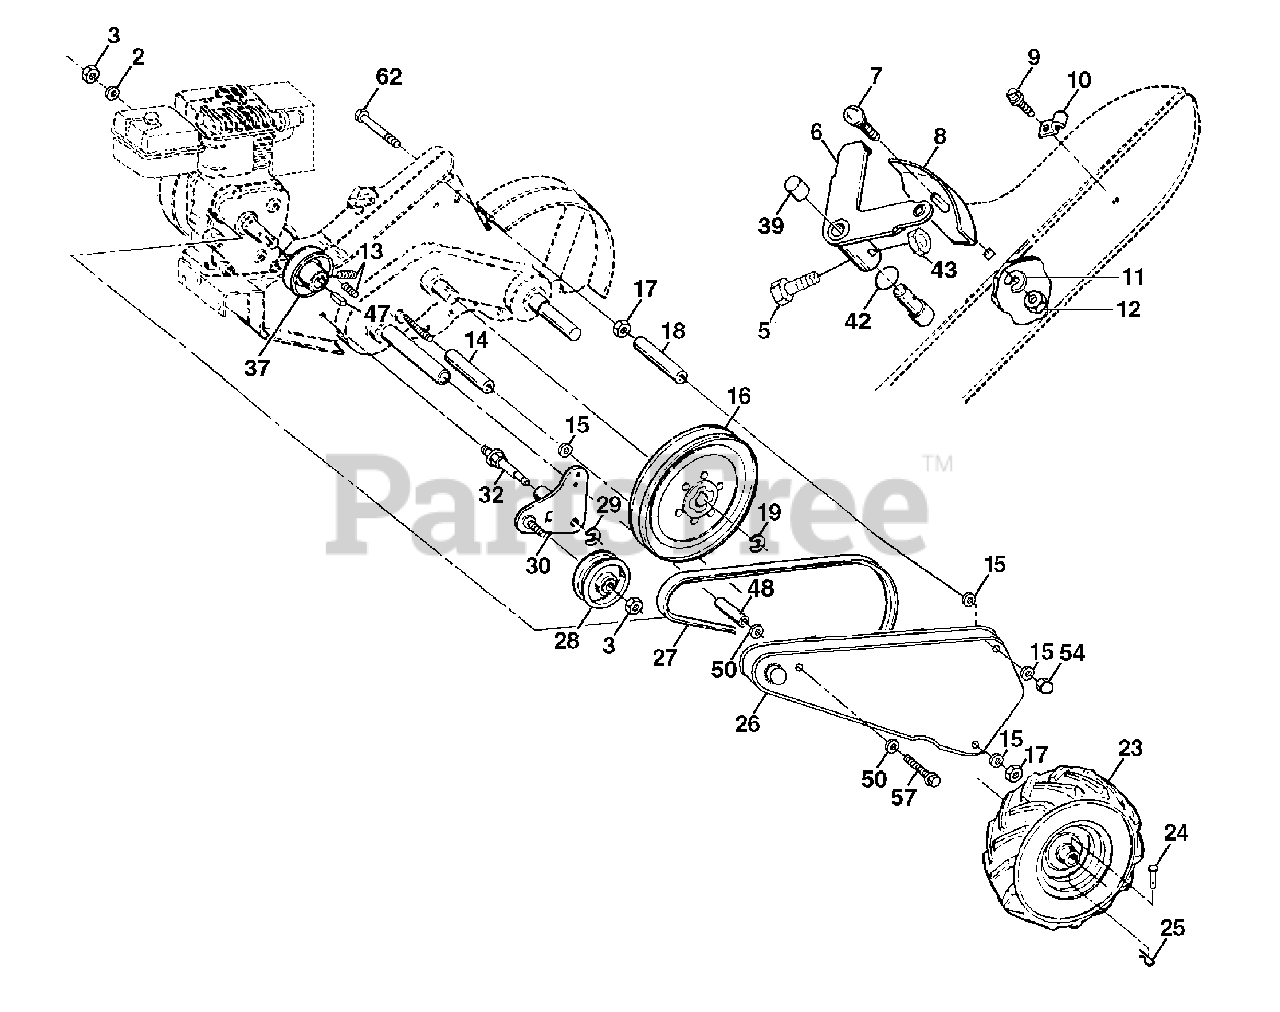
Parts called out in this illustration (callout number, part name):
2	Washer, Lock 3/8
3	Nut, Hex 3/8-16
6	Lever, Shift
7	Bolt, Carriage 1/4-20 x 1/2 Grade 5
8	Plate, Shift Indicator
9	Screw, Hex Washer Head, Slotted #10-24 x 1/2
11	Washer, Lock 1/4
12	Nut, Hex 1/4-20
13	Screw, Set, Hex 5/16-18 x 3/8
14	Spacer, Split
15	Washer 11/32 x 11/16 x 16 Gauge
16	Sheave, Transmission
17	Nut, Hex 5/16-18
19	Ring, Retainer
23	Rim
23	Tire Valve
24	Rivet, Drilled
25	Clip, Hairpin
26	Guard, Belt
28	Pulley, Idler
29	Ring, Klip
30	Bracket, Idler
32	Shaft, Idler Arm
37	Sheave, Engine
39	Cap, Plunger
43	Nut, Lock #10-24 UNC
47	Key, Square
48	Spacer, Split .523 x .718 x .700
50	Washer
54	Nut, Cap 5/16-18
57	Bolt, Hex Head 1/2-20 x 2-3/4
62	Bolt, Hex Head 5/16-18 x 4-1/2
